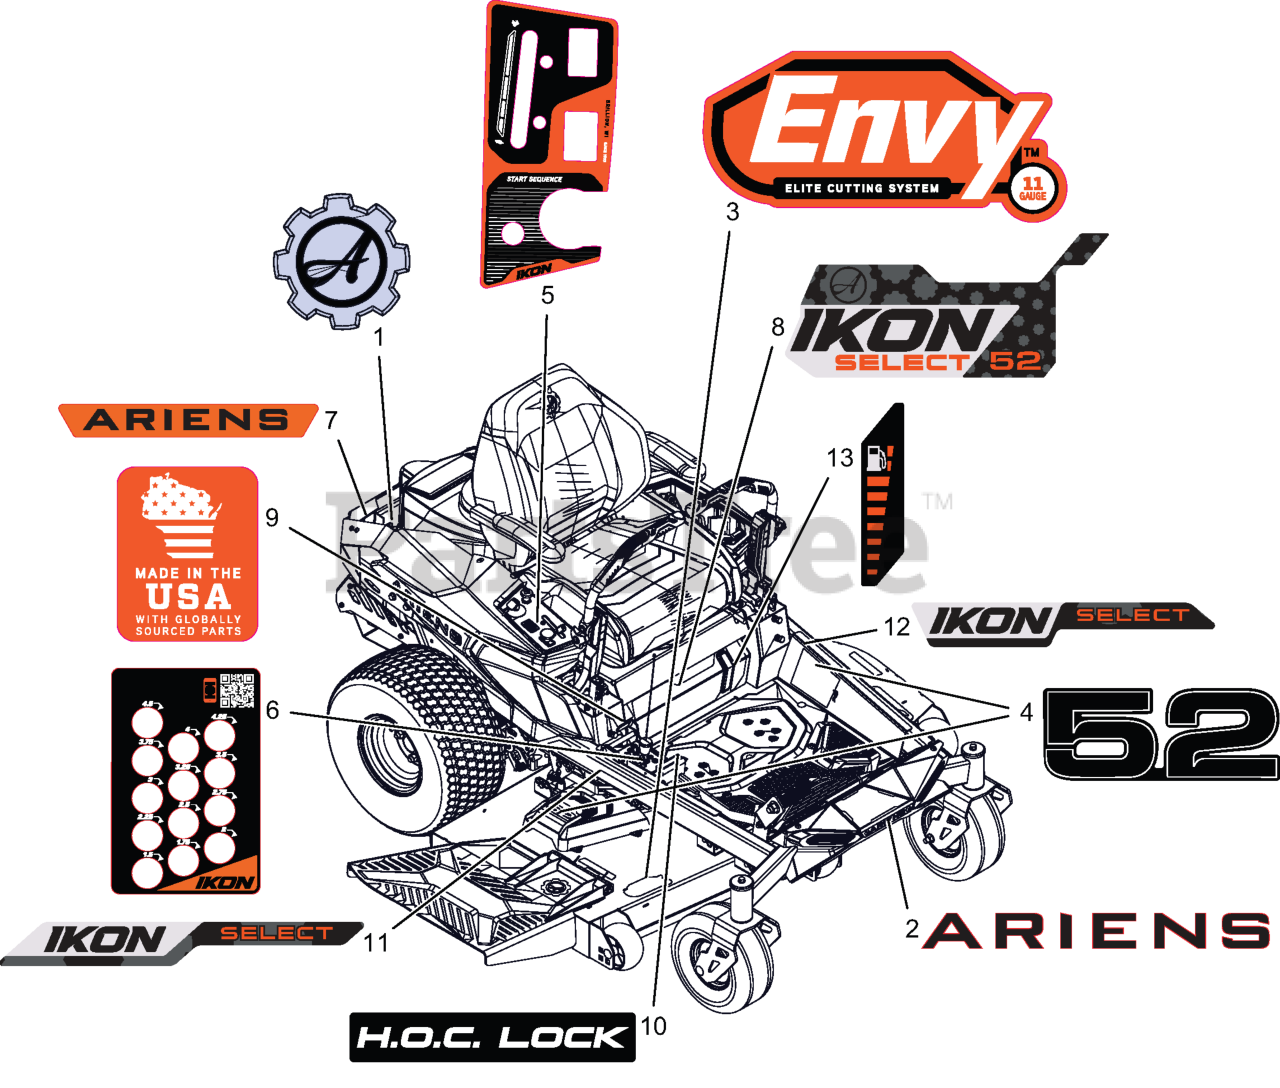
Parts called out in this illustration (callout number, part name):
1	DECAL- ARIENS GEAR BADGE
2	DECAL- ARIENS-BADGE
3	DECAL- DECK
4	DECAL- 52
5	DECAL- CONTROL PANEL
6	DECAL- HEIGHT OF CUT
7	DECAL- ARIENS
8	DECAL- IKON 52 KICKPLATE-P
9	DECAL- MADE IN USA
10	DECAL, HOC LOCK
11	DECAL, IKON SELECT FRAME - RH
12	DECAL, IKON SELECT FRAME - LH
13	DECAL, FUEL LEVEL - IKON SELECT
